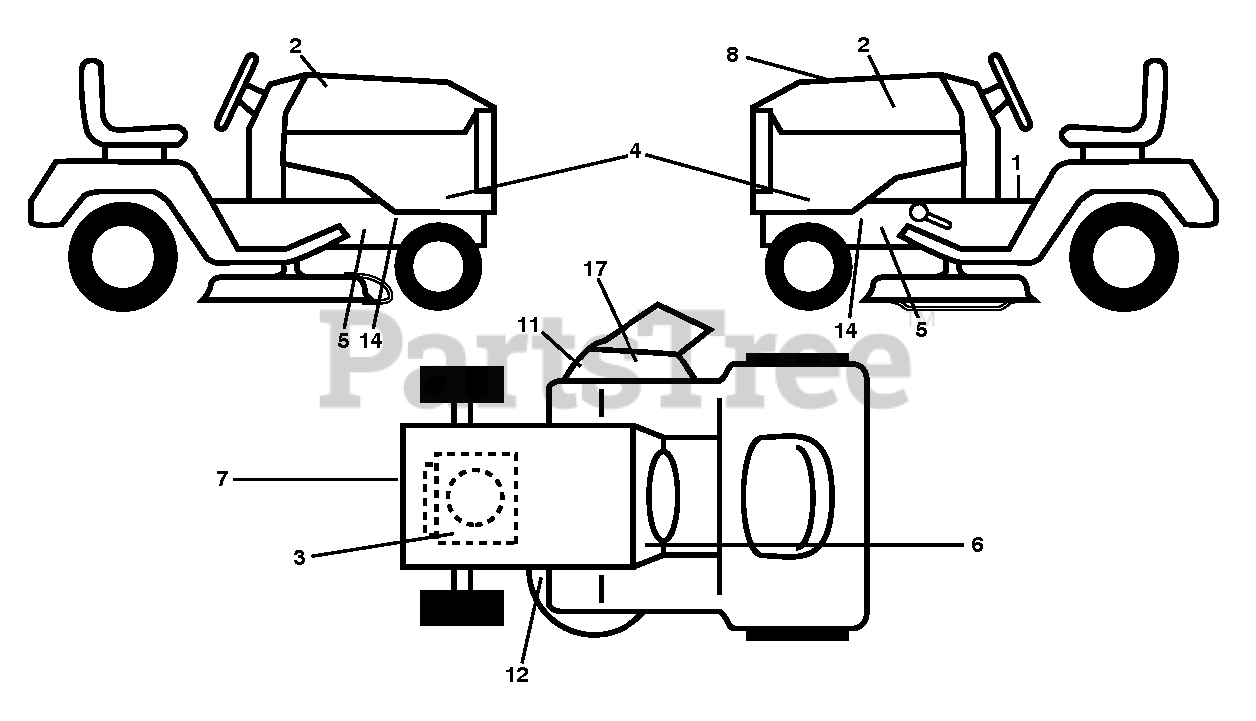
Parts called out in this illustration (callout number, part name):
1	DECAL.TRACTOR.SADDLE
2	DECAL.WB.178MM.15.HUSQ.NEWBRAN
3	DECAL.ENGINE.WARNING
4	DECAL TRACTOR SIDE PANEL DECAL
5	DECAL.CHASSIS.HOT.MUFFLER
6	DECAL.SNOWFLAKE.MS498.HUSQ
8	DECAL.RPL.LCC.352.TLW.38
11	DECAL.DFLCTR.WARNNG.CTFNGR.SYM
12	DECAL.DECK.SCH.36,38,94.NONCR
14	DECAL.WARNING.SERVCE/FIRE
17	DECAL, DECK DEFLECTOR, WARNING
